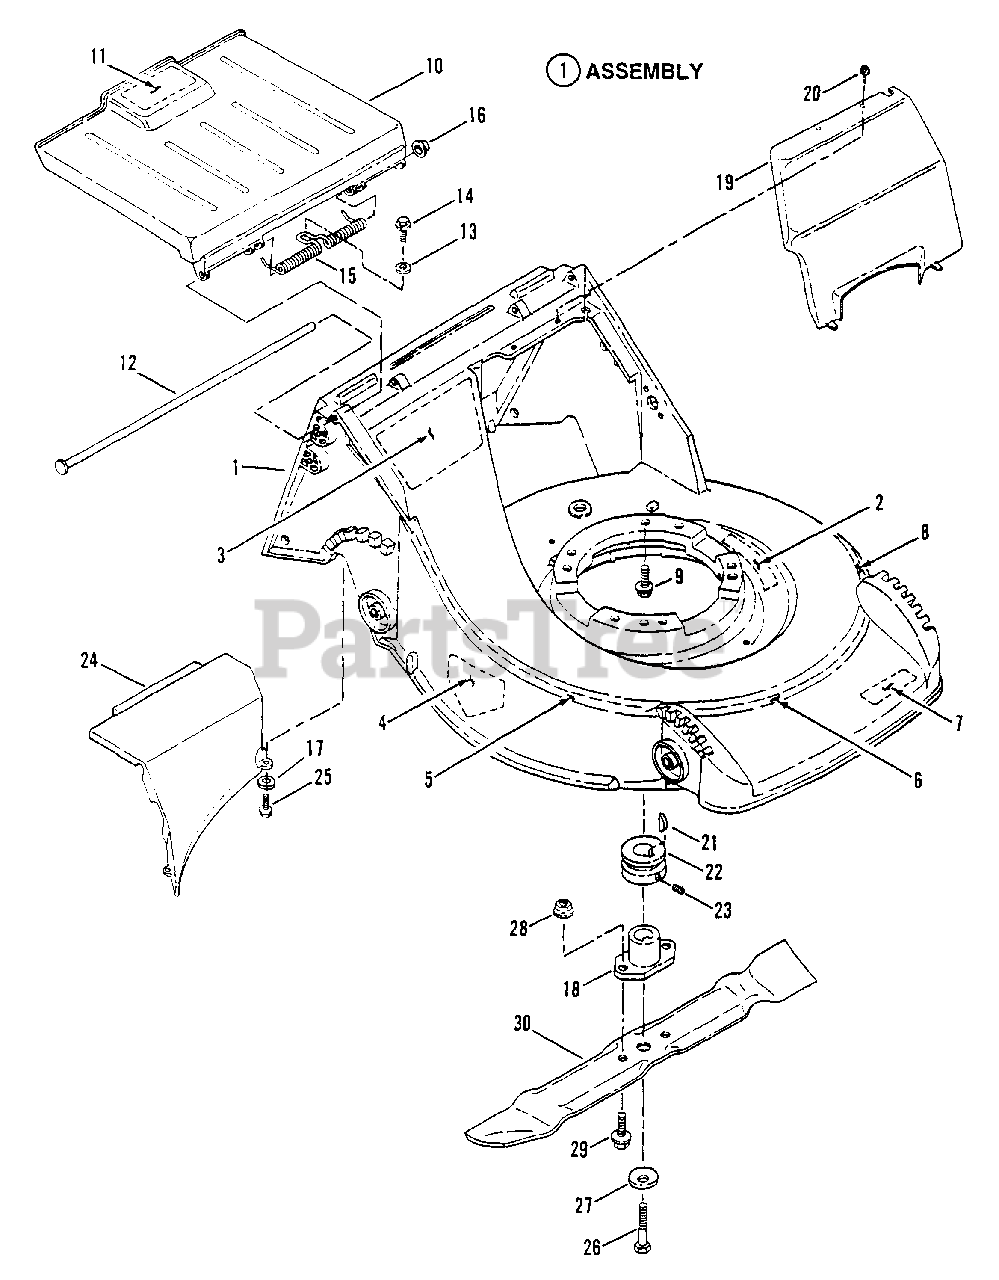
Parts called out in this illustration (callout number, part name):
1	ASSEMBLY, Deck & Decals
2	DECAL, WARNING
3	DECAL, Mulching Convertible
4	DECAL, DANGER
5	DECAL, Stripe (Right Hand Side)
6	DECAL, Stripe (Front)
7	DECAL, SNAPPER, Mulching Convertible
8	DECAL, Stripe (Left Hand Side)
9	SCREW, 3/8-16 x 1" Self-Tapping (Engine Mounting)
10	ASSEMBLY, Door/Decal
11	DECAL, Quick Change Convertible
12	ROD, Door Hinge
13	WASHER, 1/4 Flat
14	SCREW, #10-16 x 5/8" Self-Tapping
15	SPRING, Torsion
16	NUT, 5/16 Push
17	WASHER, 1/4 Flat
18	HUB, Blade Drive (Briggs Engine)
19	COVER, Drive
20	SCREW, #10-24 x 1/2" Hex Washer Self-Tap (Torx)
21	KEY, 3/16 x 5/16" #605 Woodruff (Briggs Engine)
22	PULLEY, Engine (Briggs Engine)
23	SETSCREW, 5/16-18 x 5/16" Hex Socket
24	BAFFLE, Rear
25	SCREW, 1/4-20 x 5/8" Truss Head (Torx)
26	SCREW, 3/8-24 x 2" Hex Head Cap (Gr. 5) (Briggs Engine)
27	WASHER, 3/8 Split Lock
28	NUT, 3/8-16 Hex Top Lock (Briggs Engine)
29	SCREW, 3/8-16 x 1-1/4" Hex Head Cap (Briggs Engine)
30	BLADE, 21" Cutter
